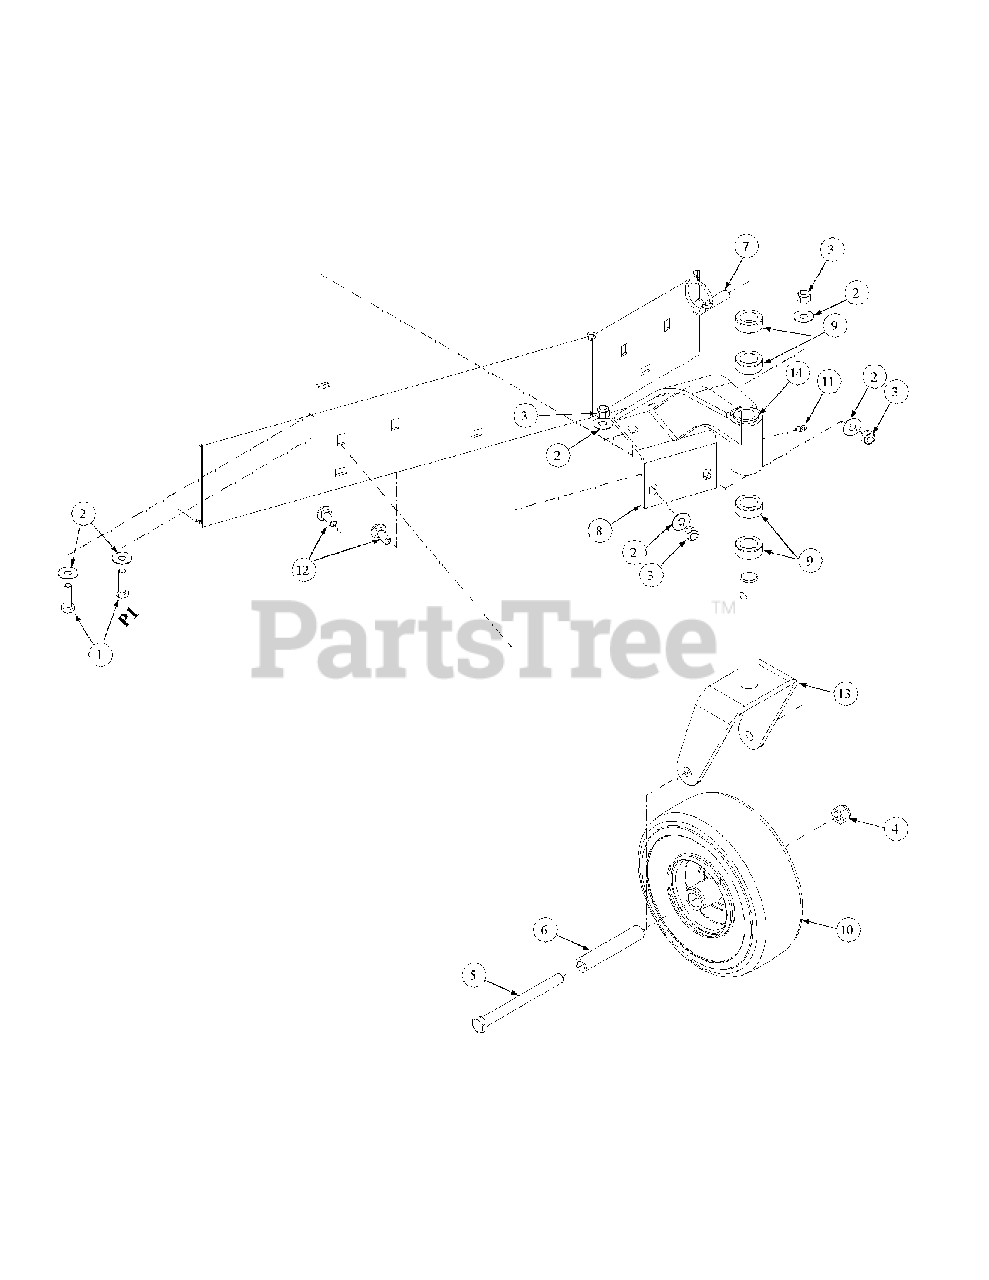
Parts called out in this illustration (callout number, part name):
1	HHCS, Standard 3/8-16 x 1-1/4
2	Flat Washer, 3/8
3	Lock Nut, Nylon Insert 3/8-16
4	Lock Nut, Nylon Insert, 1/2-13
5	HHCS, 1/2-20, 5.5 Lg
6	Spacer Wheel
7	Klik Pin, 1-3/4
8	Caster Bracket Weldment
9	Caster Spacer
10	Wheel Assembly 9.0 x 3.50
11	Grease Fitting, 1/4-28 x 3/16
12	Carriage Bolt, 3/8-16 x 1" Lg
13	Caster Yoke Weldment Assembly
14	Caster Bushing
